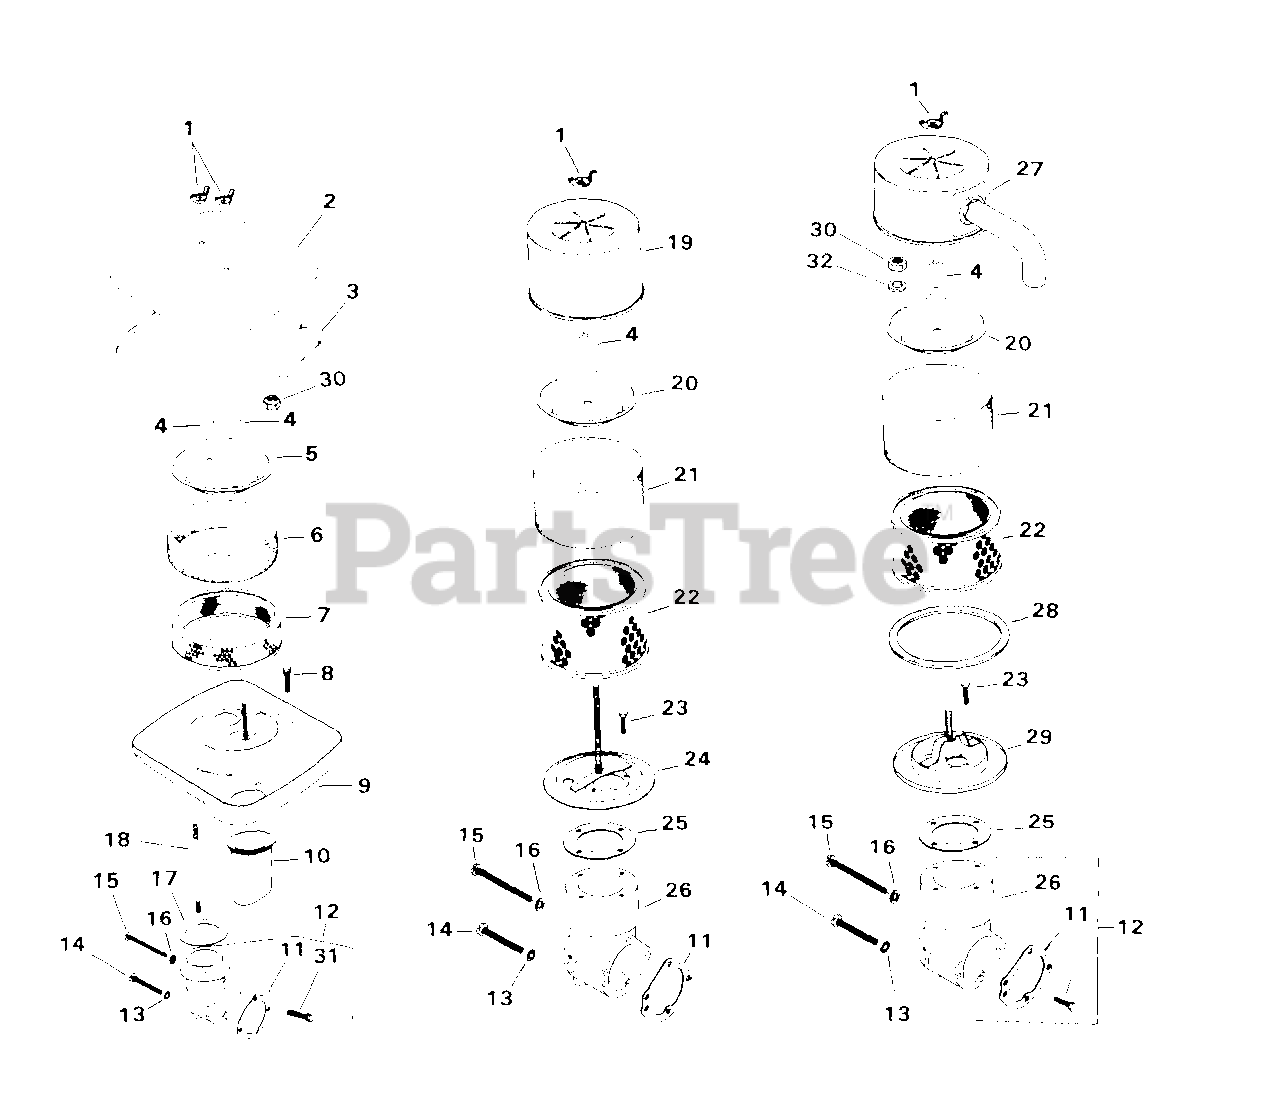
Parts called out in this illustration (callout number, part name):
1	NUT, WING 1/4-20 USE 25 100 15-S
2	COVER - (#DSC)
3	SEAL, AIR CLEANER - (#DSC)
4	SEAL, BREATHER
8	SCREW, WSH HD TAP 1/4-20X7/16" USE 25 086 106-S
9	BASE - (#DSC)
11	GASKET, AIR CLEANER ELBOW
12	KIT, ELBOW - DISCONTINUED
13	WASHER, INT TOOTH LOCK #10
14	SCREW, SLT PAN HD 10-32X1 3/4"
15	SCREW, SLT PAN HD 10-32X2 1/4"
16	WASHER, FLAT 3/16"
18	STUD,1/4-20x4-3/4" USE 25 072 10-S
31	SCREW, WSH HD TAP 1/4-20X3/4" USE 25 086 100-S
